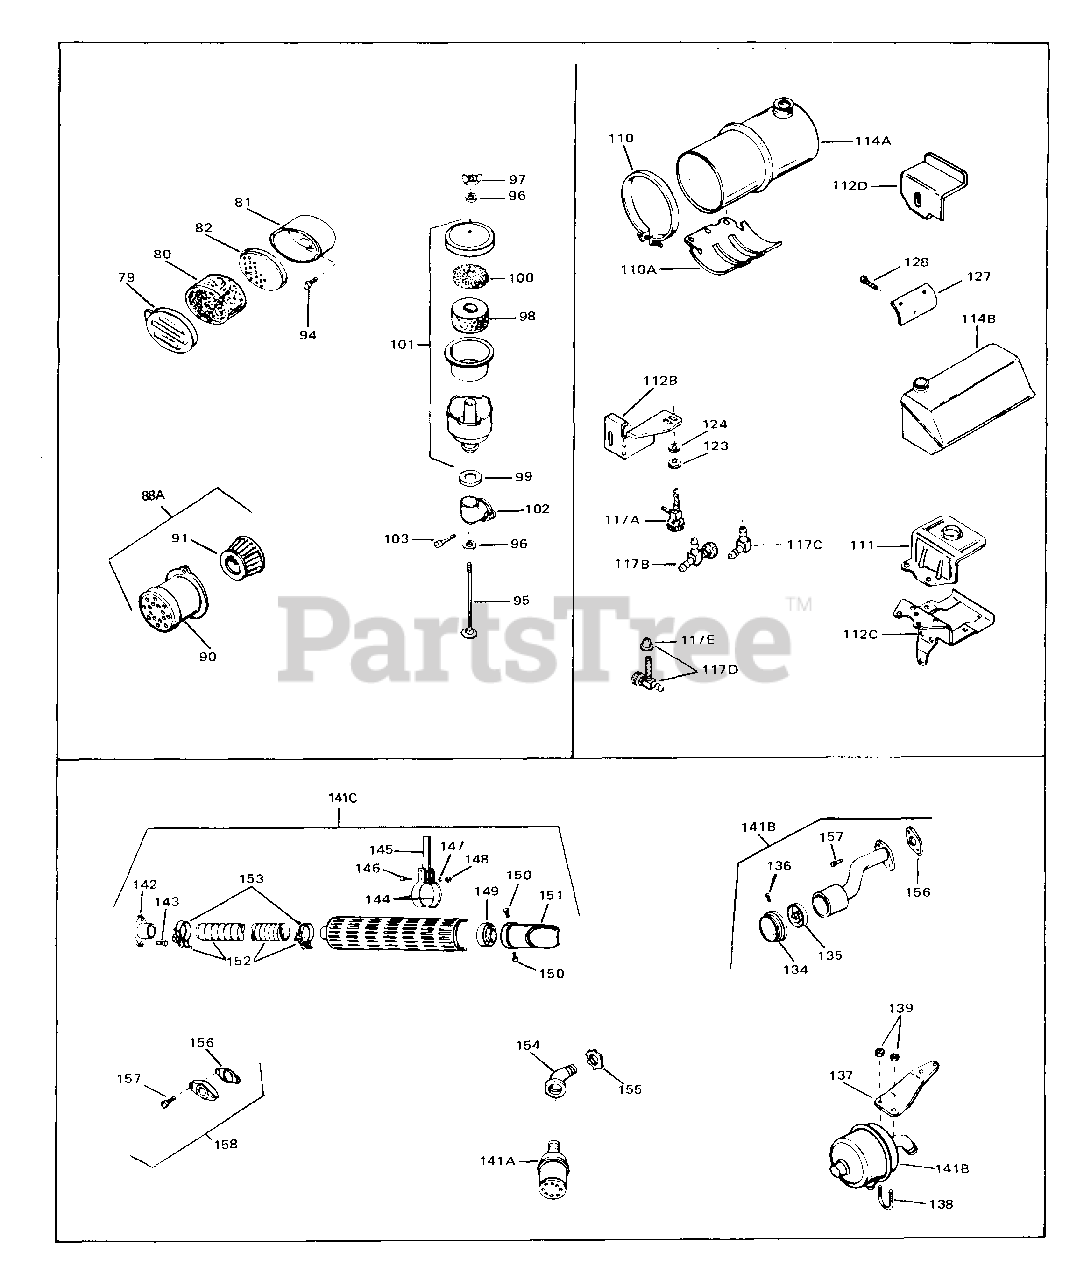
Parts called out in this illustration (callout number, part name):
5	Valve, Intake (Standard)
5	Valve, Intake (1/32" oversize)
88A	Cleaner Assy., Air (Paper)
90	Body, Air cleaner
91	Element, Air cleaner (Paper)
94	Screw, Fil. hd. Sems, 10-32 x 1/2
123	Nut & Lockwasher, 1/4-28
134	Cover, Muffler
135	Screen, Muffler
136	Screw, 8-18 x 3/8 Hex hd. self-tap
156	Gasket, Muffler
157	Screw, Fil. hd. Sems, 1/4-20 x 9/16
157	Screw, Fil. hd. Sems, 1/4-20 x 3/4
158	Muffler Adapter Kit
